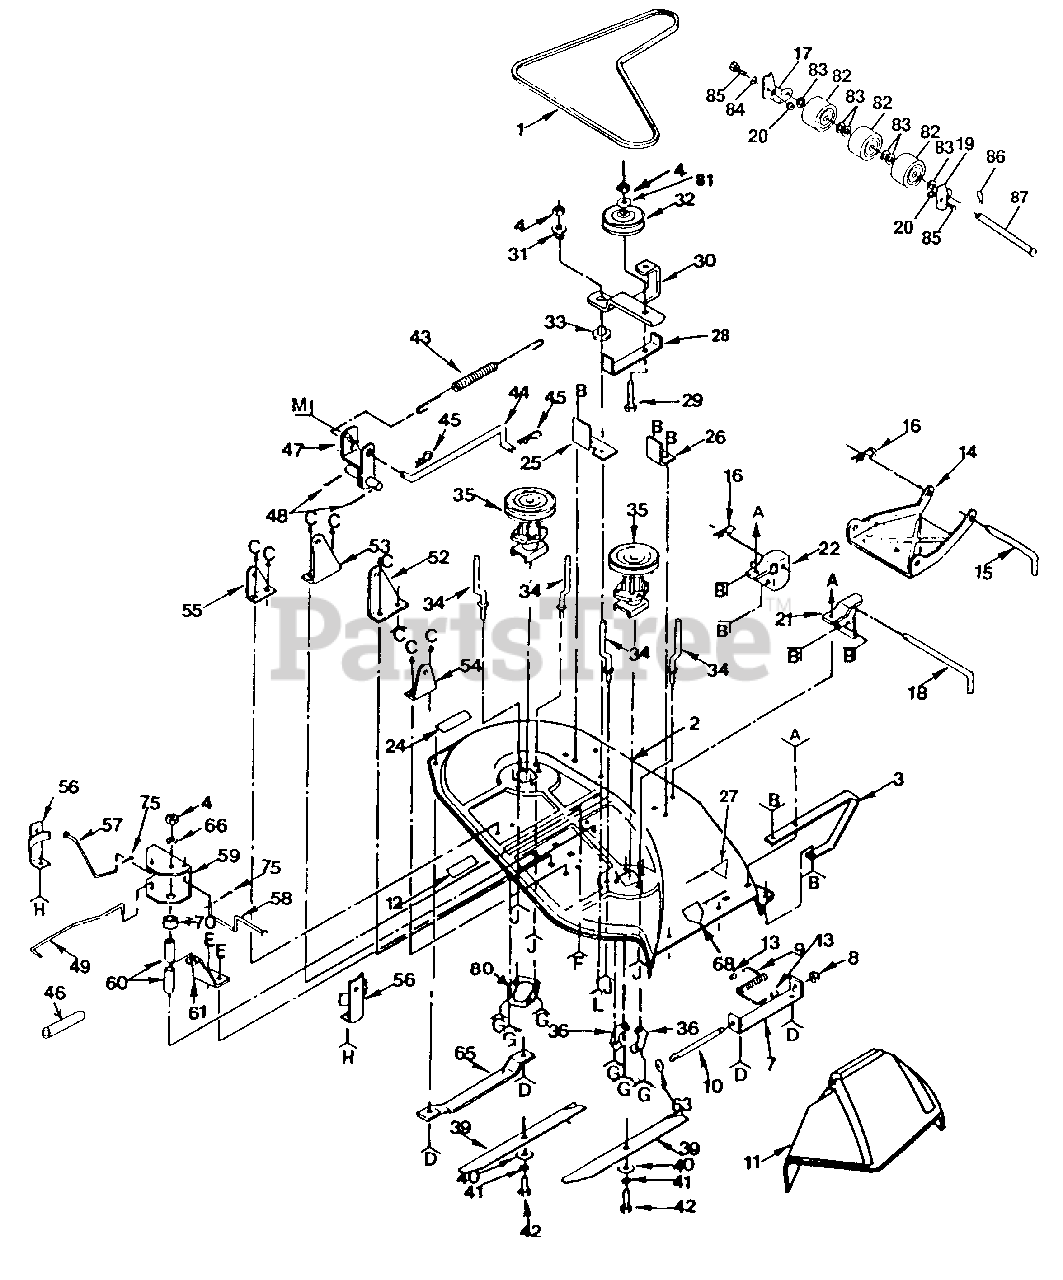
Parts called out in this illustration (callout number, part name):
2	Housing
3	Runner R.H.
4	Nut, Lock 3/8 - 16
7	Bracket, Deflector
9	Spring, Deflector
10	Rod, Hinge
11	Deflector, Shield
12	Decal, V-Belt Mower Drive
14	Link, Parallel
15	Pin, Hinge, Front
16	Spring, Retainer
17	Bracket, Nose Roller L.H.
18	Pin, Hinge, Rear
19	Bracket, Nose Roller R.H.
20	Nut, Lock 5/16 - 18
21	Bracket, Lift R.H.
22	Bracket, Lift L.H.
24	Decal, Instruction, Caution
25	Support, Arm
26	Stop, Deck, Front
27	Decal, Safety Standard
28	Guide, Belt
29	Bolt 3/8-16 x 2
30	Arm, Idler Assembly
32	Pulley, Idler
33	Washer, Wear 1/16
34	Keeper, Belt
35	Mandrel, Assembly
36	Plate, Support, Mandrel
39	Blade
40	Washer 13/32 x 1-1/4 x 12 Ga.
41	Washer, Lock 3/8
42	Bolt, Hex 3/8-24 x 1-1/2 Gr. 5
43	Spring , Ext.
44	Rod, Clutch, Mower
45	Spring, Retainer
47	Rock Shaft Assembly
48	Pin, Cotter 3/16 x 1
49	Rod, Brake, Primary
52	Bracket, Pivot R.H.
53	Bracket, Pivot L.H.
54	Bracket, Susp., Rear R.H.
55	Bracket, Susp., Rear L.H.
56	Brake Assembly
57	Rod, Brake, Secondary L.H.
58	Rod, Brake, Secondary R.H.
59	Bracket, Brake, Pivot
60	Spacer, Brake
61	Bracket, Support
63	Washer 11/32 x 5/8 x 16 Ga.
65	Runner L.H.
66	Washer 13/32 x 1 x 14 Ga.
68	Decal, Warning
75	Pin, Cotter 3/32 x 1/2
80	Plate, Support L.H
81	Washer, 13/32 x 13/16 x 16 Ga.
82	Roller.Nose.
83	Washer 15/32 x 1 x 10
84	Washer 1/2 x 1 x 16 ga.
85	Bolt, hex 5/16-18 x 3/4
86	Pin, Cotter. 1/8 x 3/4
87	Pin, Pivot.
